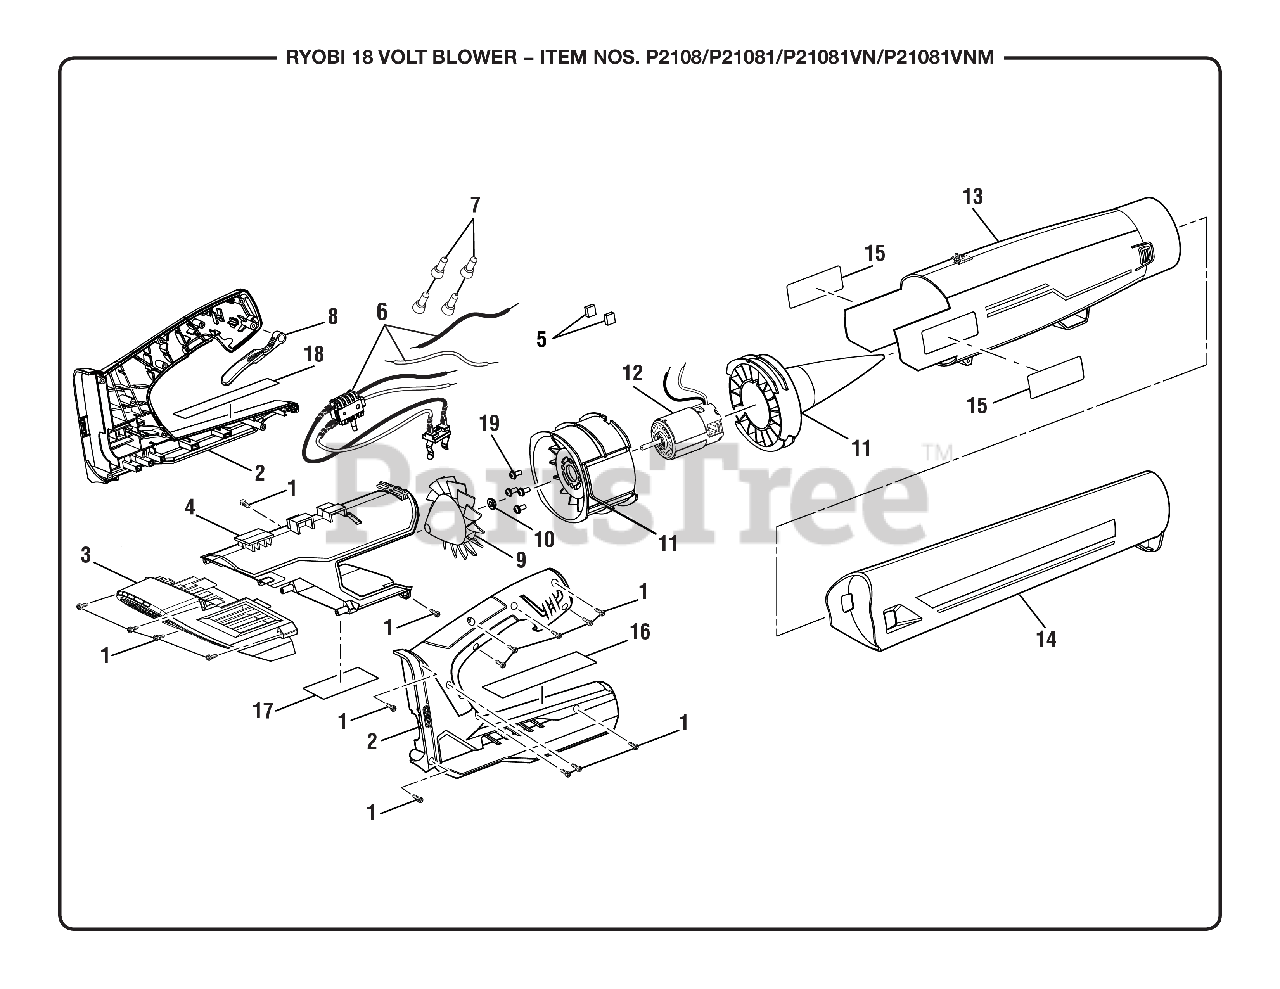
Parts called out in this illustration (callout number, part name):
1	Screw (M4 x 14 mm, T15 Torx Pan Hd.))
2	Handle Assembly
3	Inlet Guard
4	Inlet Housing Assembly
5	Rubber Block
6	Switch and Contact Plate Assembly
7	Wire Connector (Closed End)
8	Trigger Assembly (Variable Speed)
9	Fan Blade
11	Tail Cone Assembly
13	Blower Housing Outlet Assembly
14	Blower Tube
15	Logo Label (Ryobi)
16	Warning Label
17	Data Label
18	Warning Icon Label
19	Screw w/Lock Washer (M5 x 8 mm, Pan Hd.)
